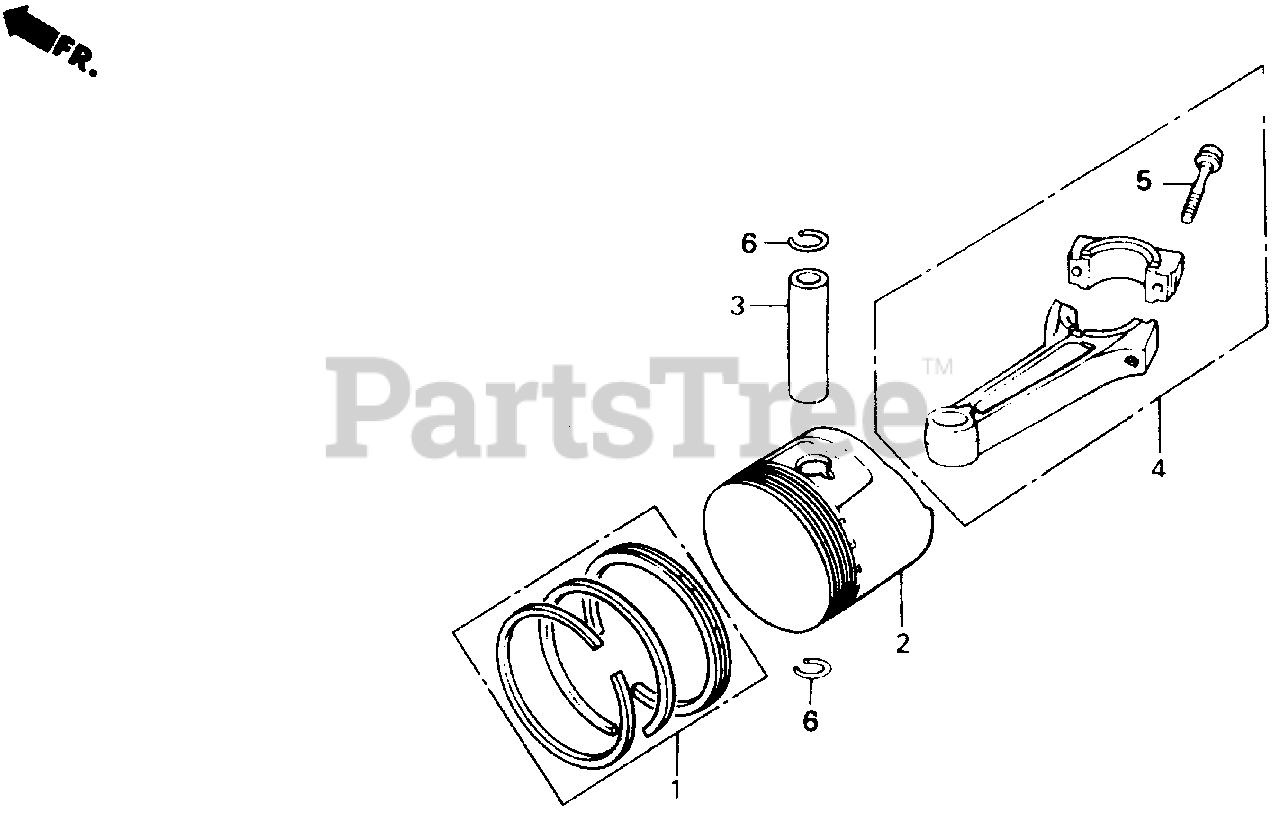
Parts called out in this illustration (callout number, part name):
1	RING SET, PISTON (STD) (NIPPON)
1	RING SET, PISTON (0.25) (NIPPON)
1	RING SET, PISTON (0.50) (NIPPON)
1	RING SET, PISTON (0.50) (TEIKOKU)
2	PISTON (STD)
2	PISTON (0.25)
2	PISTON (0.50)
3	PIN, PISTON
4	ROD ASSY., CONNECTING
4	ROD ASSY., CONNECTING (0.25 LOWER SIZE)
5	BOLT, CONNECTING ROD
6	CLIP, PISTON PIN (20MM)
